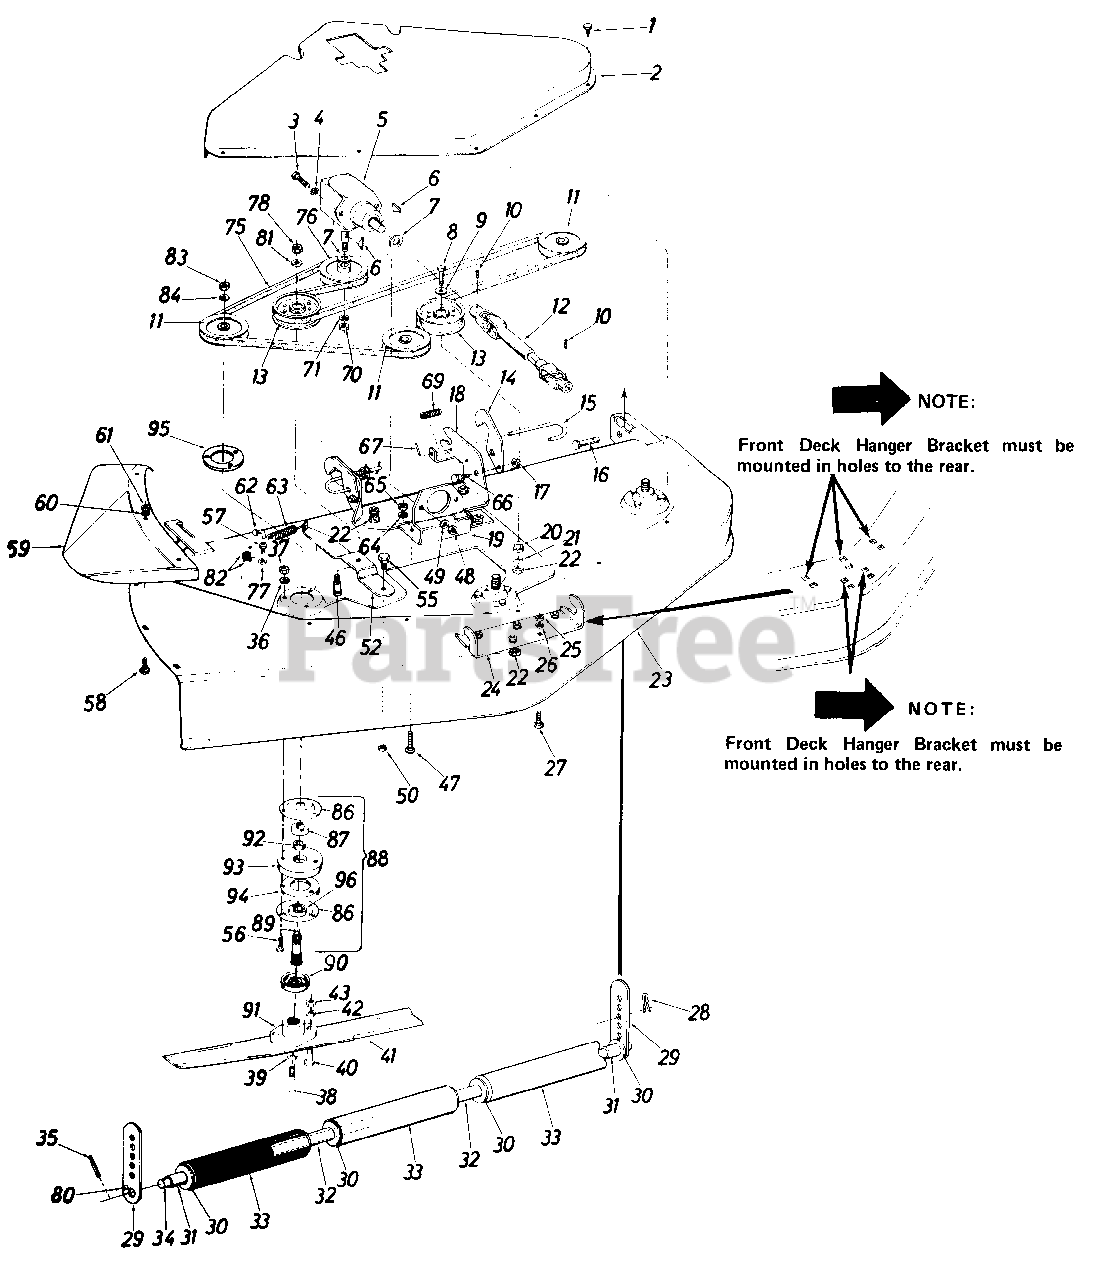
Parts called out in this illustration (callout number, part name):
1	Hex B Tap Scr. 1/4-20 x .38" Lg.
4	Ext. L-Wash. 3/8" Scr.*
5	Right Angle Drive
6	#9 Hi-Pro Key 3/16 x 3/4" Dia.
7	Fl-Wash. 29/32 I.D.
8	Hex Scr. 3/8-16 x 2.25" Lg.*
9	Fl-Wash. 3/8" I.D.
10	Sq. Hd. Set Scr. 3/8-16 x .50" Lg. Cup
11	Deck Pulley
12	Universal Drive Shaft Ass'y.
13	Deck Idler Pulley
14	Hanger Lock
15	Release Pin
16	Clevis Pin .500 Dia.
17	Hex Cent. L-Nut 5/16-18 Thd.
21	L-Wash. 3/8" Scr.*
22	Hex Nut 3/8-16" Thd.*
26	L-Wash. 5/16" Scr.*
27	Carriage Bolt 5/16-18 x 1.00" Lg.*
28	Internal Cotter Pin
30	Fl-Wash. .75 I.D. x 1.5 O.D.
31	Spacer .758 I.D. x 1.25 O.D. x .530
34	Roller Shaft
35	Roll Pin 3/16 x 1.25
36	L-Wash. 5/16" Scr.*
37	Hex Cent. L-Nut 5/16-24 Thd.
38	Hex Scr. 3/8-24 x .75" Lg. Thd. Rolling
39	L-Wash. 3/8" Scr. H.D.
40	Hex Scr. 5/16-24 x 1.00" Lg.
41	Blade 17"
42	L-Wash. 5/16" Scr.*
43	Hex Cent. L-Nut 5/16-24 Thd.
46	Hex Scr. 5/8-18 x 1.31" Lg.
47	Carriage Bolt 5/16-18 x .75"
48	Hex Nut 3/8-16 Thd.*
49	L-Wash. 3/8" Scr.*
50	Hex Cent. L-Nut 7/16-14
56	Hex Scr. 5/16-24 x 1.50" Lg. (Grade 5)
57	Hex Nut 1/4-2 Thd.*
58	Carriage Bolt 5/16-18 x .75" Lg *
60	L-Wash. 5/16" Scr.*
61	Hex Nut 5/16-18 Thd.*
62	Hook Bolt
63	Extension Spring
64	L-Wash. 5/16" Scr.
65	Hex Nut 5/16-18 Thd.*
66	Shld. Scr.
67	Roll Pin 1/8" Dia.
69	Compression Spring
70	Hex Cent. L-Nut 5/8-18 Thd.
71	L-Wash. 5/8" Scr.*
75	"V"-BeltASect. 117" Lg.
76	Drive Pulley
77	Hex Cent. L-Nut 1/4-20 Thd.
78	Hex Cent. L-Jam Nut 5/8-18 Thd.
80	Spring Pin Spiral 1/4" Dia. 1.00"
81	Fl-Wash..62" I.D.
82	Ext. L-Wash. 1/4" Scr.*
83	Hex Jam Nut 5/8-18 Thd.
84	L-Wash. 5/8" I.D.*
86	Bearing Housing
87	Ball Bearing
88	Deck Spindle Ass'y.
89	Spindle
90	Bearing Shield
91	Blade Adapter
92	Spacer
93	Spindle Spacer Plate
94	Reinforcement Plate
95	Spindle Reinforcement Plate
96	Open Bearinq Housing
12649-0638	GUARD-CHUTE - MTD/TROY-BILT RED (0638)
12649-0648	GUARD-CHUTE - TECH GRAY (0648)
12650-4008	Height Adjuster - WINE RED (4008)
